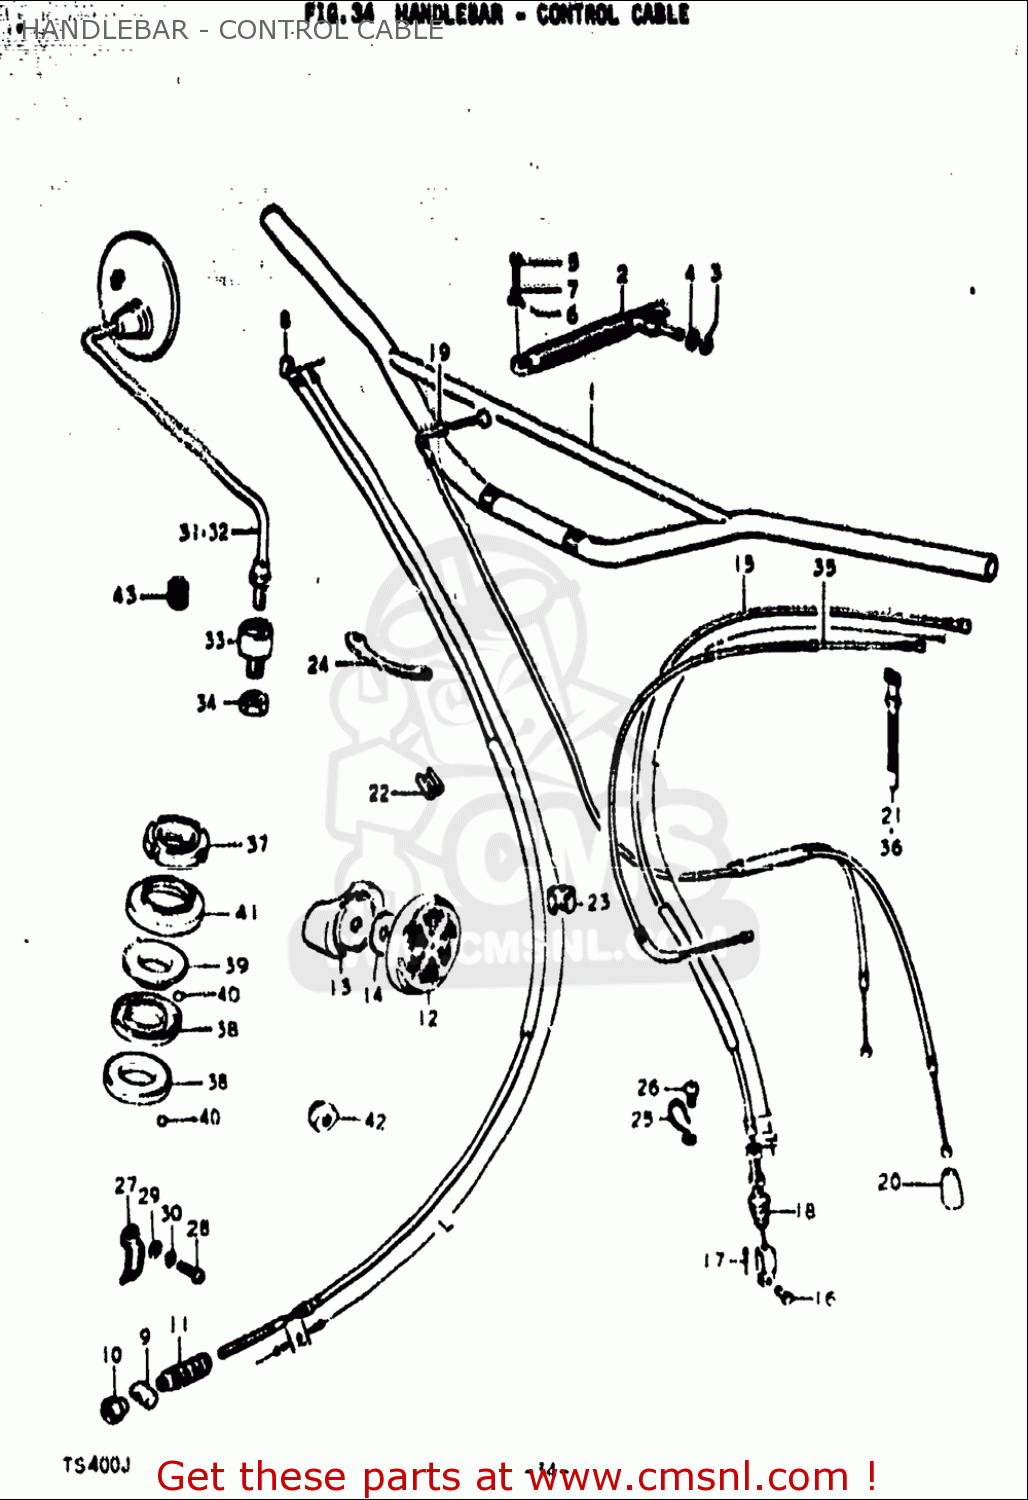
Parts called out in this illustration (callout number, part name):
3	E RING
4	WASHER
5	BOLT
6	WASHER
7	WASHER,LOCK
8	CABLE,FR BRAKE
9	PIN(13X18)
10	NUT
11	SEAL,DUST
12	REFLEX REFLECTOR,RR
13	SPACER
14	WASHER(6.5X20X1.2)
15	WIRE,CLUTCH
16	PIN(L:15)
17	PIN
19	CABLE ASSY,THROTTLE
20	SEAL,DUST(7X18X30)
21	CLAMP
22	CLIP
23	CLIP
26	SCREW
27	CLAMP
28	SCREW
29	WASHER
30	WASHER,LOCK
31	MIRROR ASSY,RE
32	MIRROR ASSY,LEFT
34	NUT
36	CLAMP(L:120)
37	NUT,STEERING STEM(25X44X10)
38	LACE,STEERING INNER LWR
39	LACE,STEERING OUTER UPR
40	BALL
41	DUST SEAL,STEERING UPR
